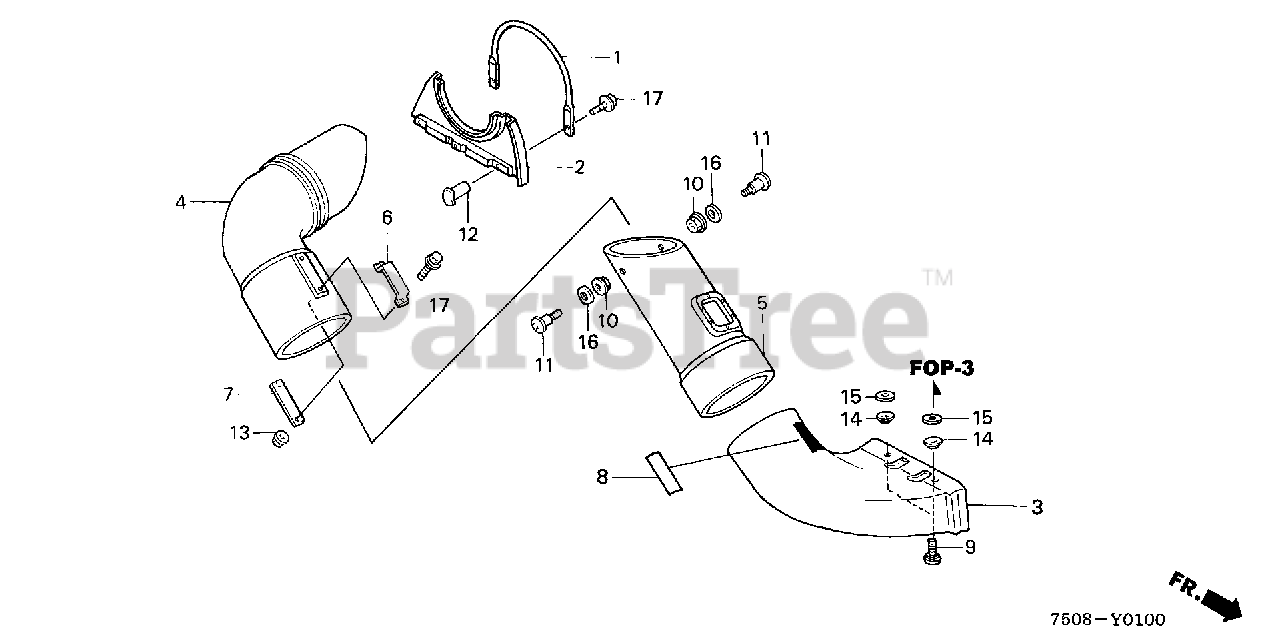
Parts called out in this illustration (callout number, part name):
1	SUPPORT, CHUTE
3	CHUTE (LOWER)
4	CHUTE (UPPER)
5	CHUTE, MIDDLE
6	HANDLE, CHUTE
7	BASE, HANDLE
8	LABEL, CHUTE (E)
8	LABEL, CHUTE
9	BOLT, SPECIAL (8X20)
10	NUT, SELF-LOCK (8MM)
11	BOLT, CHUTE
12	NUT, PIPE (6MM)
13	NUT, SELF-LOCK (6MM)
14	WASHER (8X24)
15	WASHER, LOCK (5/16)
16	WASHER, PLAIN (8MM)
17	BOLT, FLANGE (6X16)
